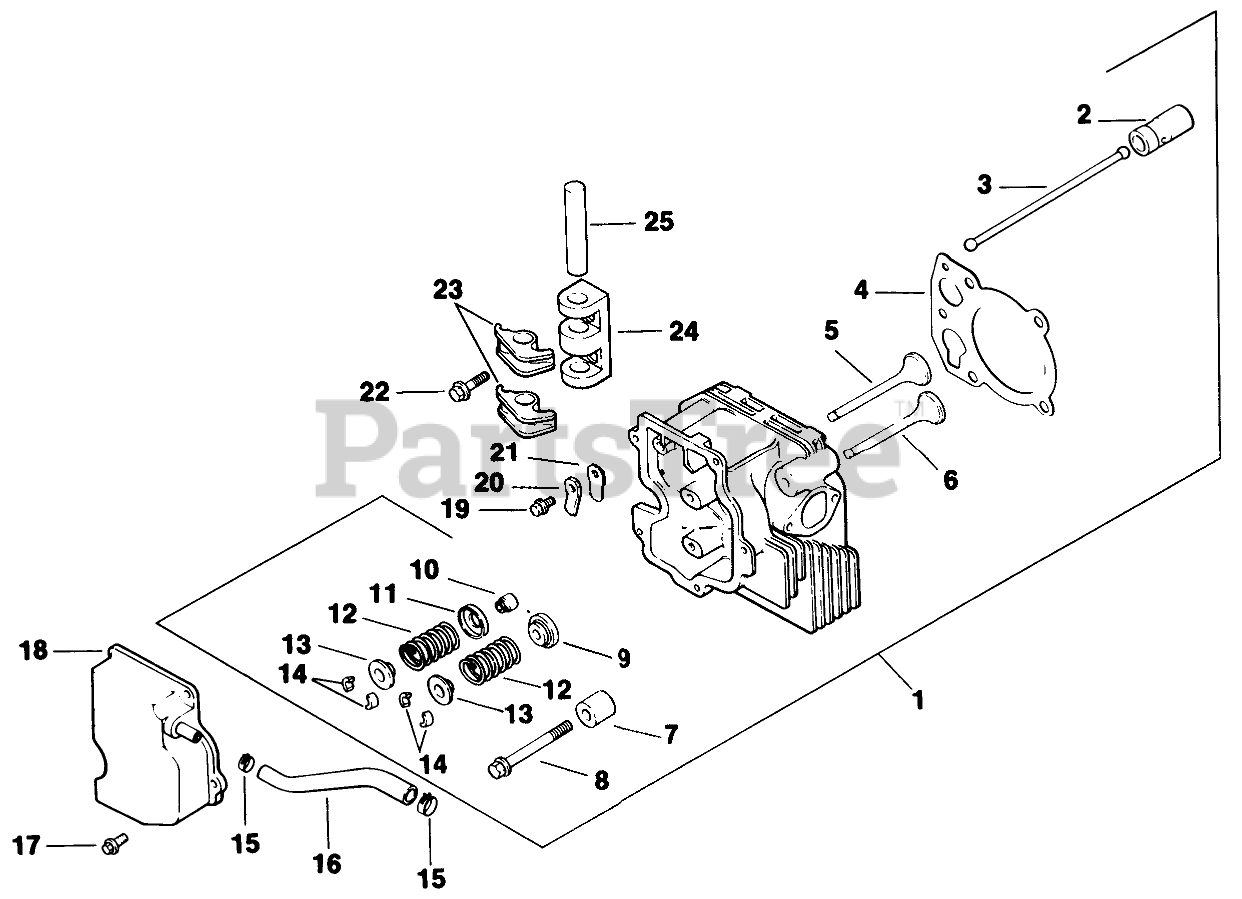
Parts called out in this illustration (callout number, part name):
1	Kit Cylinder Head
2	Lifter-Valve
3	Rod-Push
4	Gasket-Cylinder Head
5	Valve-Intake STD
6	Valve-Exhaust STD
7	Spacer-Head Bolt
8	Screw-Cylinder Head
10	Seal
11	Retainer-Spring
12	Pulley
13	Cap-Valve Spring
14	Kit-Retainer
15	Clamp
16	Hose-Breather
17	Screw
18	Cover-Valve
20	Retainer-Reed
22	Screw
23	Arm-Rocker
24	Bridge-Rocker Arm
25	Shaft-Rocker Arm
